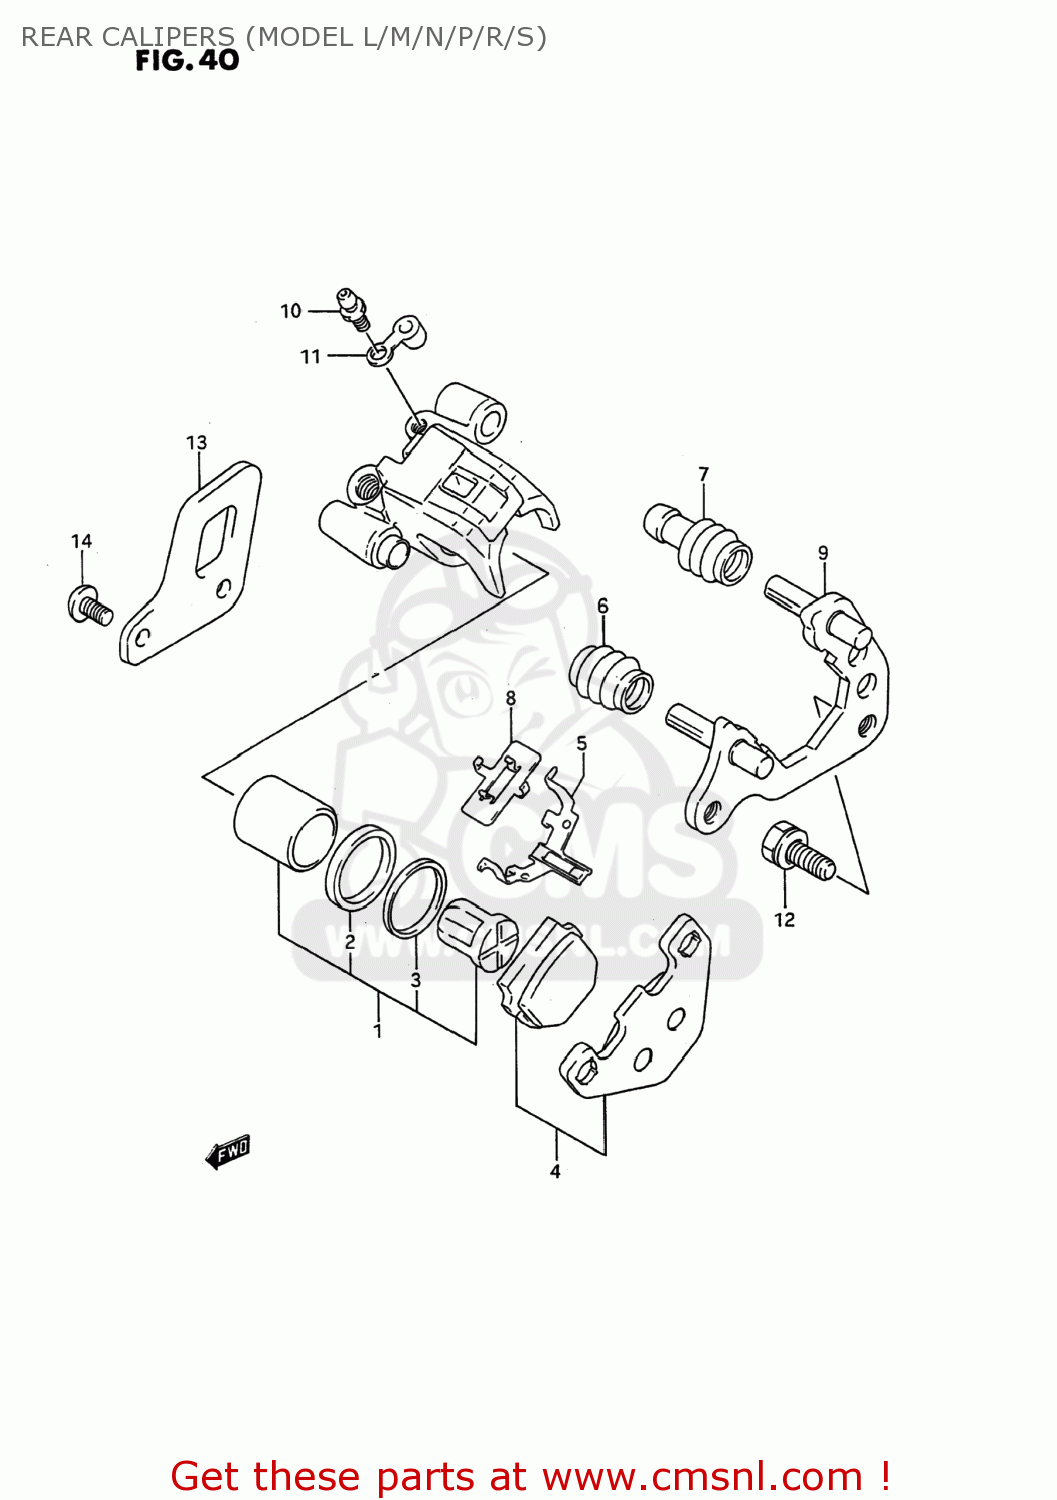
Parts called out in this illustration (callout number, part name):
1	PISTON SET
2	SEAL,PISTON
3	SEAL,WIPER
4	PAD SET (NAS)
5	SPRING,PAD
6	BOOT,AXLE
7	INSULATOR,AXLE
8	SHIM
9	CARRIER,CALIPER
10	BLEEDER
11	CAP,BLEEDER
12	BOLT(8X18)
13	GUARD,RR CALIPER
14	SCREW(6X12)
